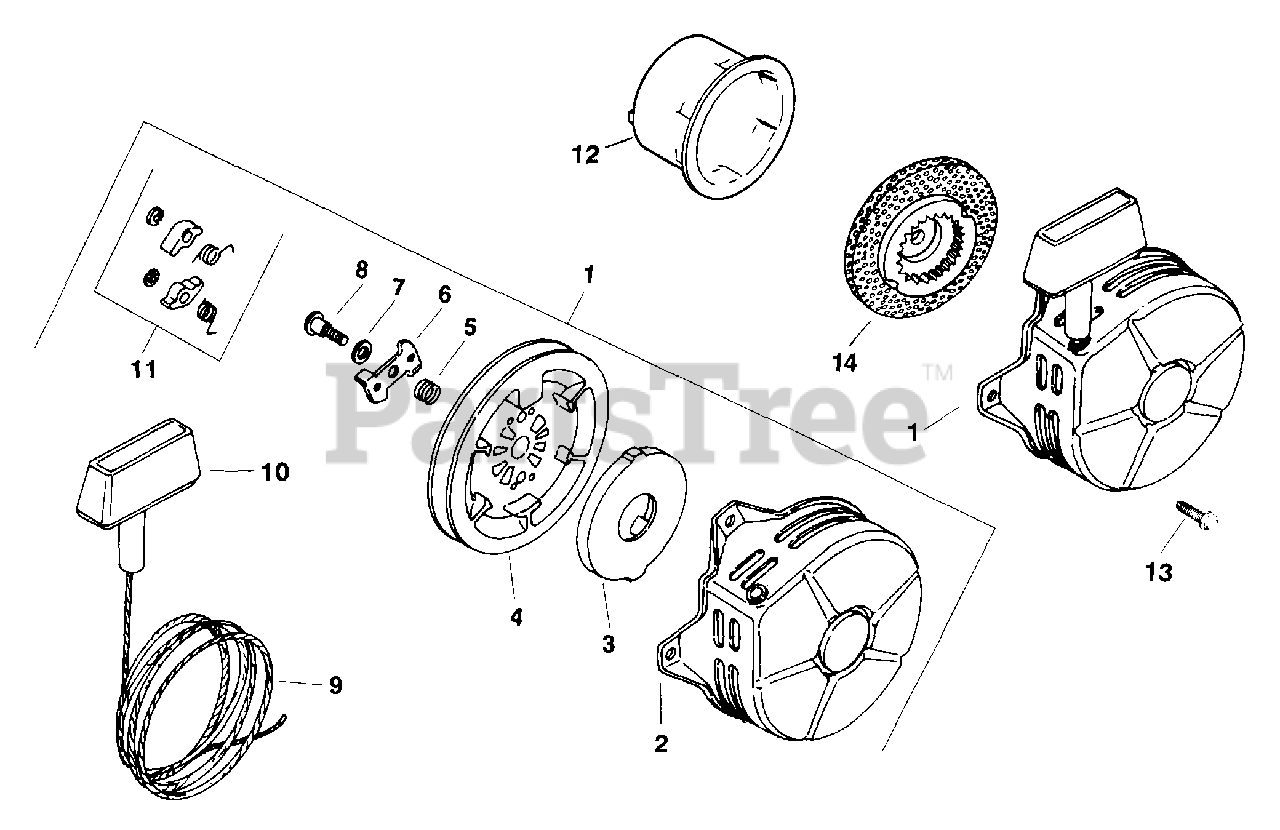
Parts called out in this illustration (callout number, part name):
1	STARTER - USE 41 755 26
2	HOUSING - DISCONTINUED
3	SPRING & KEEPER ASSEMBLY - DISCONTINUED
5	SPRING - DISCONTINUED
6	CAM - (#DSC)
8	SCREW - DISCONTINUED
9	ROPE - USE 15 160 01
10	HANDLE - USE 25 166 01
11	KIT, PAWL REPAIR - (#DSC)
12	CUP - DISCONTINUED
13	SCREW, FLG HD 10-24X1/4"
